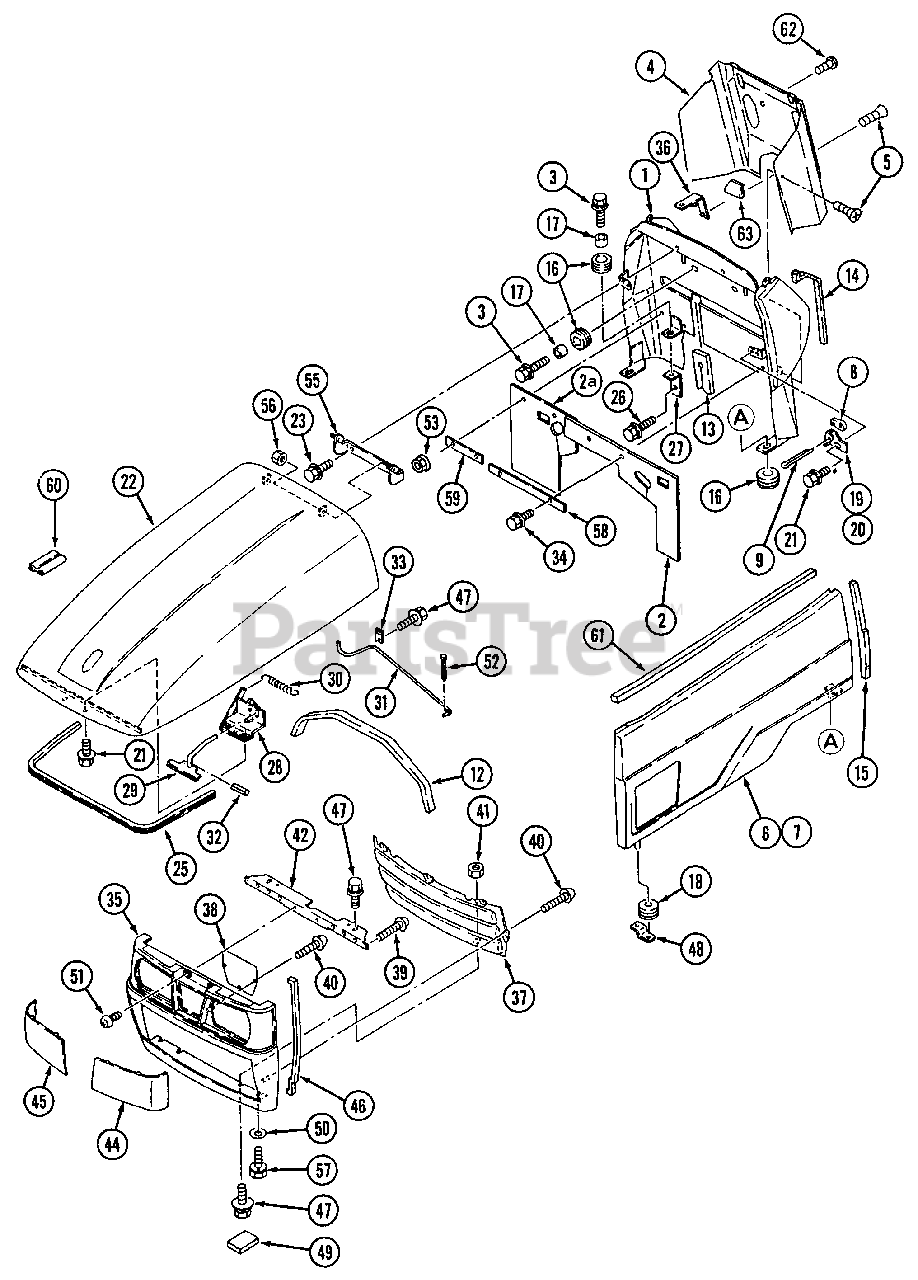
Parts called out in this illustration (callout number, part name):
4	Cover, Panel Rear
6	Cover, Side L.H.
7	Cover, Side R.H.
14	Seal, Foam
28	Bracket, Lever
39	Screw, Tapping
42	Support, Grille
44	Cover Lamp, L.H.
45	Cover Lamp, R.H.
52	Pin
55	Bracket, Hood
61	Rubber, Cushion
